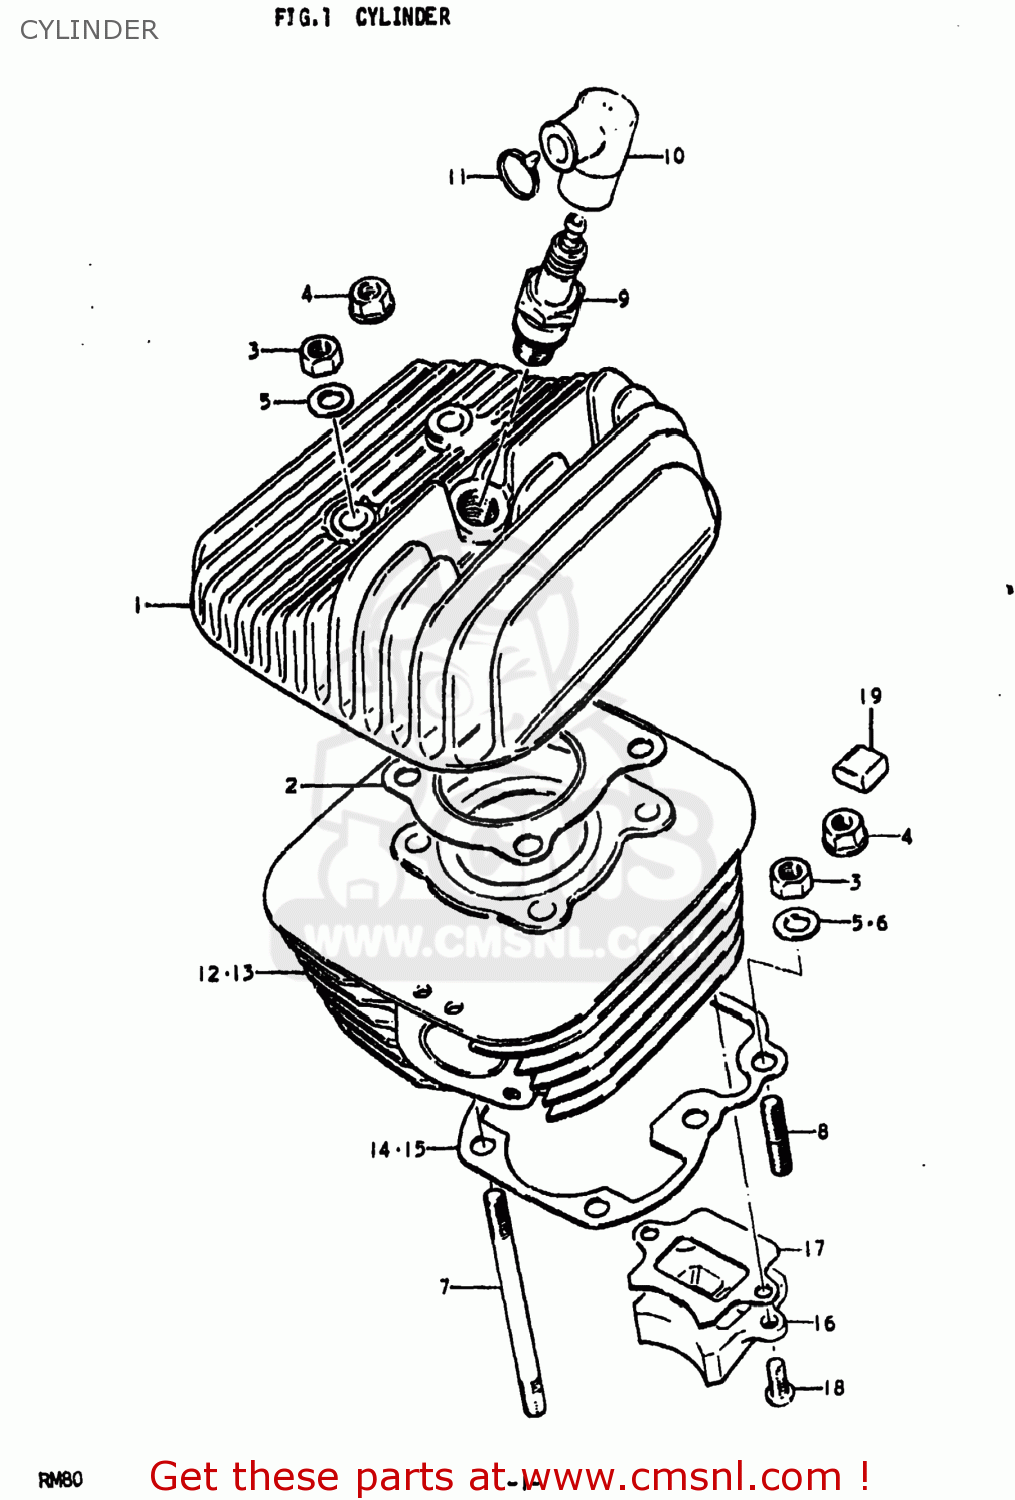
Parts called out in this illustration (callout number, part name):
1	HEAD,CYLINDER
2	GASKET,CYLINDER HEAD (NAS)
3	NUT
4	NUT
5	WASHER
6	WASHER
7	BOLT,STUD
8	STUD 8X20
9	PLUG,SPARK
10	CAP,SPARK PLUG
11	CLAMP
12	CYLINDER
13	CYLINDER
14	GASKET,CYLINDER
15	GASKET,CYLINDER (MCA)
16	VALVE ASSEMBLY,REED
17	GASKET,REED VALVE (MCA)
18	SCREW
19	PAD,CYLINDER
